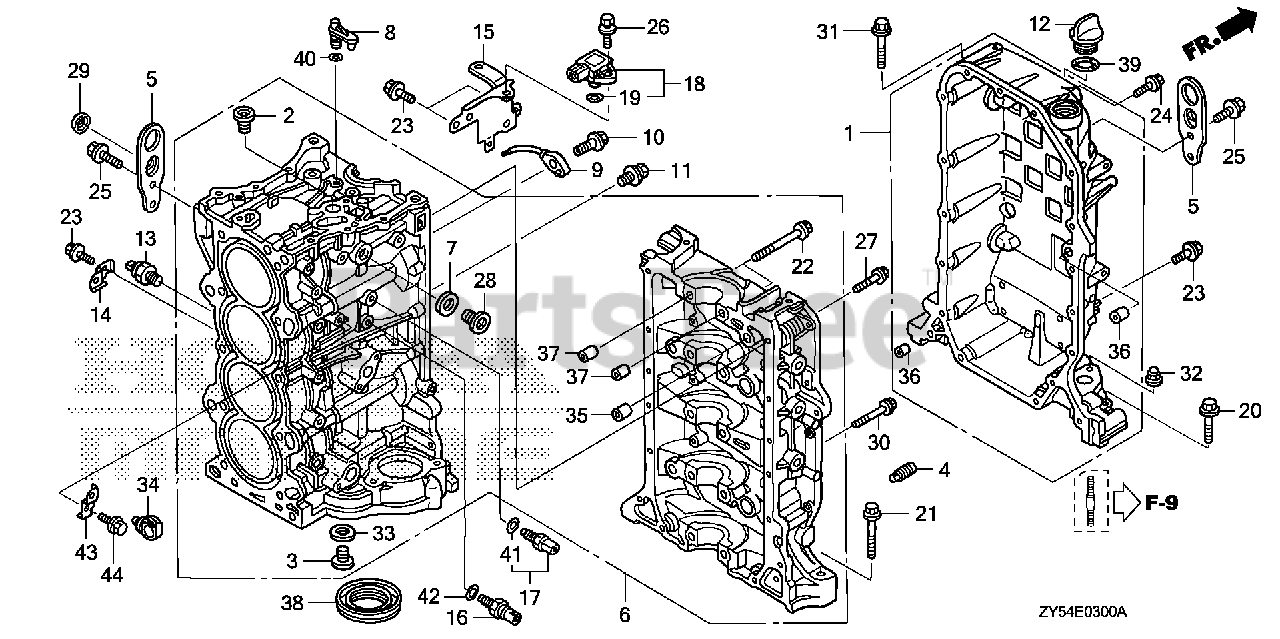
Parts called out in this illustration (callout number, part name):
1	CRANKCASE
2	BOLT, SEALING (20MM)
3	BOLT, SEALING (28MM)
4	ORIFICE, BLOCK (LOWER)
5	HANGER, ENGINE
6	BLOCK ASSY., CYLINDER *NH8* (DARK GRAY)
6	BLOCK ASSY. *NH8*
7	WASHER, SEALING (22MM)
8	ORIFICE, OIL JET
9	BODY, OIL JET
10	BOLT, OIL JET
11	BOLT-WASHER (8X10)
12	CAP, OIL
14	BRACKET, CLIP B
15	BRACKET D, HARNESS CLIP
16	SWITCH ASSY., OIL PRESSURE
16	SENSOR, OIL PRESSURE
17	SENSOR ASSY., WATER TEMPERATURE
18	SENSOR ASSY., MAP
19	O-RING
20	BOLT, FLANGE (8X55)
21	BOLT, FLANGE (12X83)
22	BOLT-WASHER (11X95)
23	BOLT, FLANGE (6X14) (CT200)
24	BOLT, FLANGE (6X25)
25	BOLT, FLANGE (8X20)
26	BOLT-WASHER (5X18)
27	BOLT, FLANGE (8X35)
28	BOLT, SEALING (22MM)
29	CAP, BOLT (8MM)
30	BOLT, FLANGE (8X50)
31	BOLT, FLANGE (10X70)
32	NUT, FLANGE CAP (10MM)
33	WASHER, SEALING (28MM)
34	CLIP, HARNESS
35	PIN, DOWEL (18X22)
36	PIN, DOWEL (13X20)
37	PIN, DOWEL (13X14)
38	OIL SEAL (80X98X10)
38	OIL SEAL (80X98X10) (ARAI)
39	O-RING (26X2.7)
40	O-RING (6.5X1.5)
41	O-RING (9.5X1.9)
42	O-RING (13X1.5) (ARAI)
43	BRACKET, CLIP B
44	BOLT, FLANGE (6X14) (CT200)
